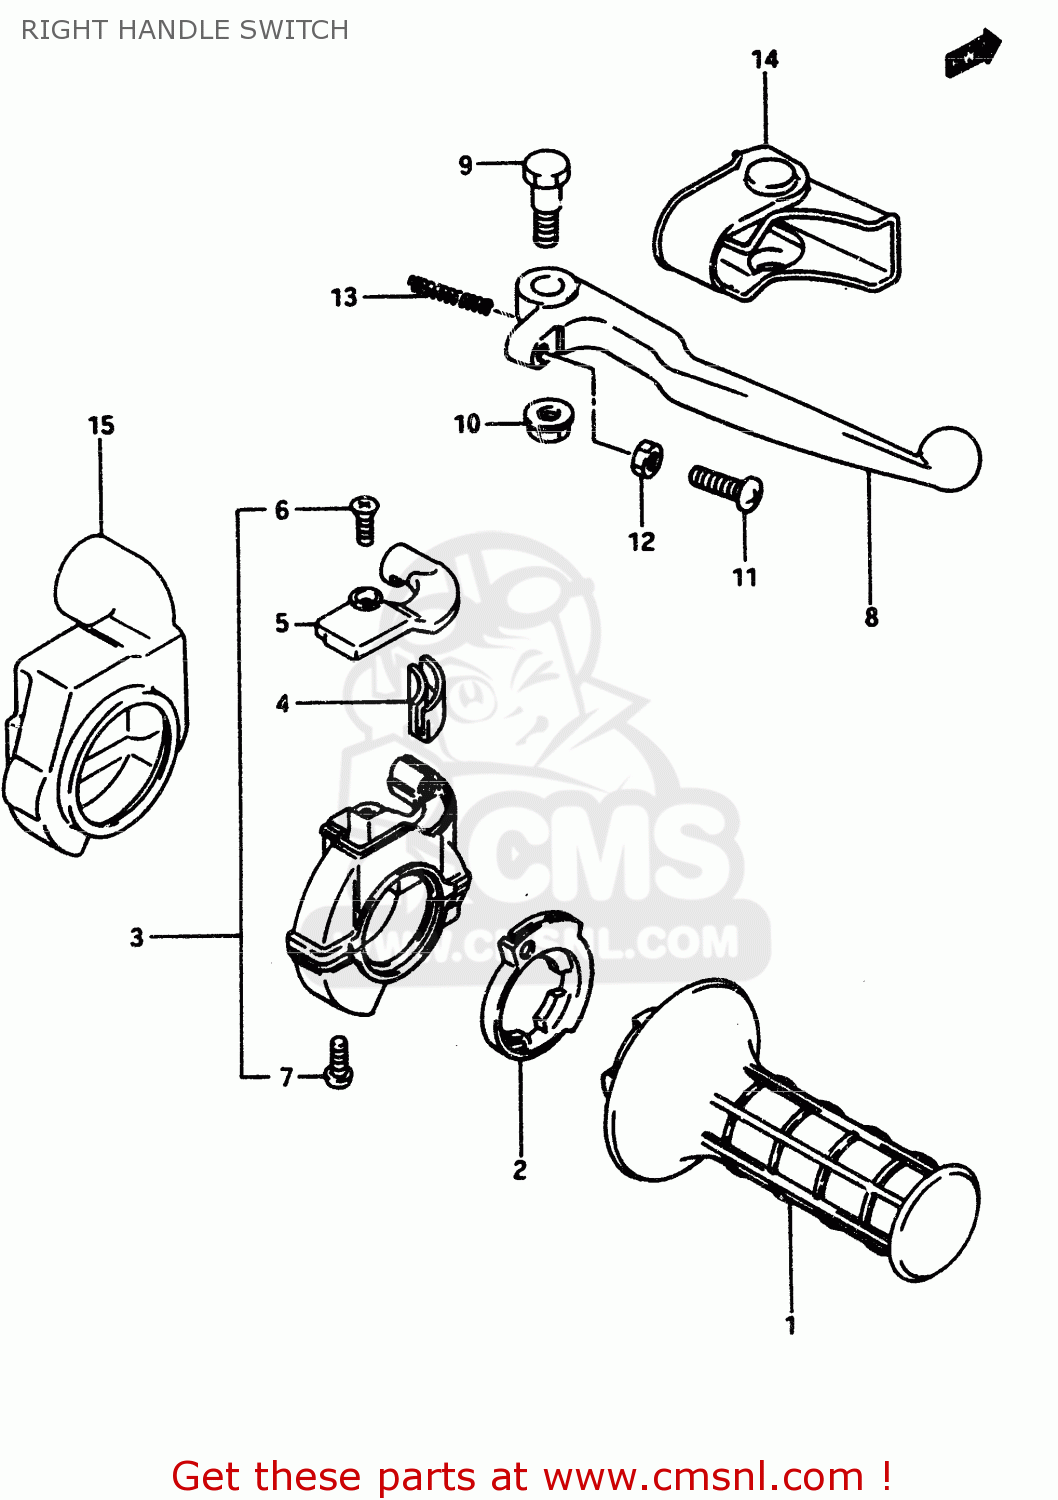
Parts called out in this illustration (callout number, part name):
1	GRIP,THROTTLE
2	ROTOR,THROTTLE GRIP
3	CASE ASSY,THROTTLE
4	GUIDE PIECE,THROTTLE
5	COVER,THROTTLE CASE
6	SCREW
7	SCREW
8	LEVER,BRAKE
9	BOLT,BRAKE LEVER
10	NUT,BRAKE LEVER
11	BOLT,LEVER
12	NUT ,5MM
13	SPRING,RETURN
14	COVER,BRAKE LEVER
15	COVER,THROTTLE CASE
